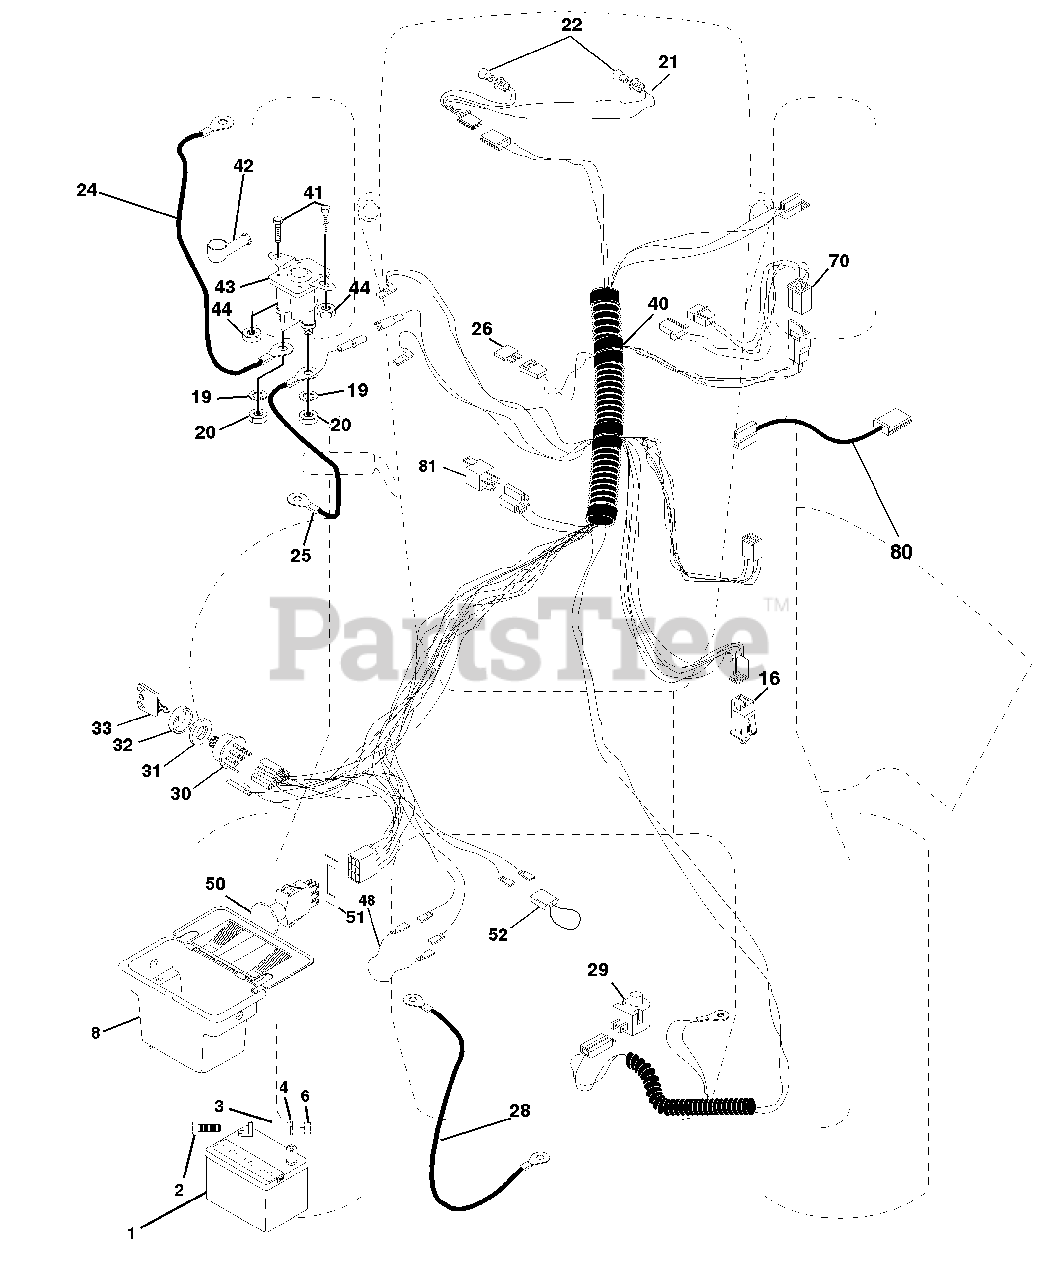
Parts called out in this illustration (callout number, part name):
1	Battery 12 Volt 25 AMP
2	Bolt Hex Hd 1/4-20 UNC X 3/4
3	Washer 9/32 X 5/8 X 16 Ga.
4	Washer Lock Hvy Helical 1/4
6	Nut Fin Hex 1/4-20 UNC
8	Case Battery Mech Hinge
16	Switch Interlock Push-In
19	Washer Lock 1/4
20	Nut Jam Hex 1/4-20 UNC
21	Harness Asm Light W/4152j
22	Bulb Light #1156
24	Cable Battery 6 Ga 11" red
25	Cable Battery 6 Ga 44" red w/16 wire
26	Fuse 30 AMP Auto Green
28	Cable Ground 6 Ga 12" black
29	Switch Plunger Normal Op Olive
30	Switch Ign 4 pos w/lights
31	Nut Ignition
32	Cover Sw Ignition
33	Key Ign Modelled Generic
40	Harness Ign.
41	Bolt Blk Fin Hex 1/4 - 20 x 1/2
42	Cover Terminal Red
43	Solenoid
44	Nut Keps Hex 1/4-20 UNC
48	Adapter Ammeter Rectangular
50	Switch, PTO 3PDT Black Delta 96
51	Ring Retainer PTO
52	Protection Wire Loop
70	Harness, Eng. B&S 14 OHV Dual
80	Harness, Clutch EVX
